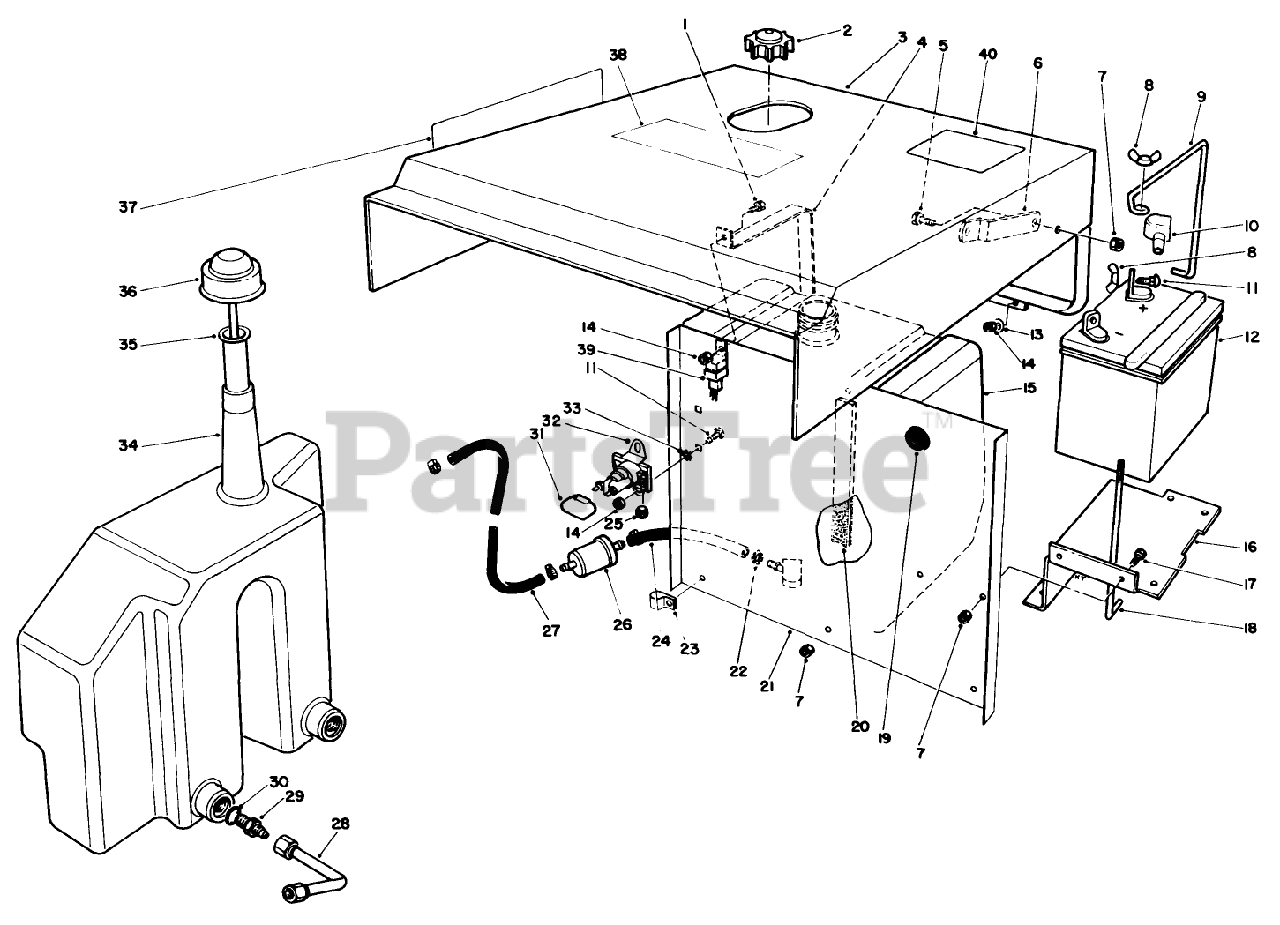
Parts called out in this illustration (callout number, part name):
1	SCREW-HH
2	GAS CAP ASM
3	Hood
4	Strap-Fuel Tank
5	SCREW-HH
6	UPPER HOOD STOP
7	NUT-LOCK, NI
8	NUT-WING
9	BATTERY CLAMP
10	BOOT-TERMINAL, RED
11	BOLT-CARR
12	Battery
13	WASHER-FLAT
14	NUT-LOCK, NI
15	TANK-FUEL
16	Support-Battery
17	SCREW-HH
18	ROD-SUPPORT, BATTERY
19	GROMMET
20	TANK SPONGE
21	HEAT SHIELD B
22	CLAMP-HOSE
23	CLAMP-WORM
24	HOSE-FUEL
25	NUT-HEX
26	FUEL FILTER
27	HOSE-FUEL
28	TUBE ASM
29	FITTING-STRAIGHT
30	O-RING
31	SOLENOID COVER
32	Solenoid
33	WASHER-LOCK/EXT
34	OIL RESERVOIR
35	SCREEN-FILLER
36	CAP WA
37	DECAL - PROLINE 118
38	DECAL-REFUELING
39	RELAY
40	DECAL - SERVICE INSTR.
